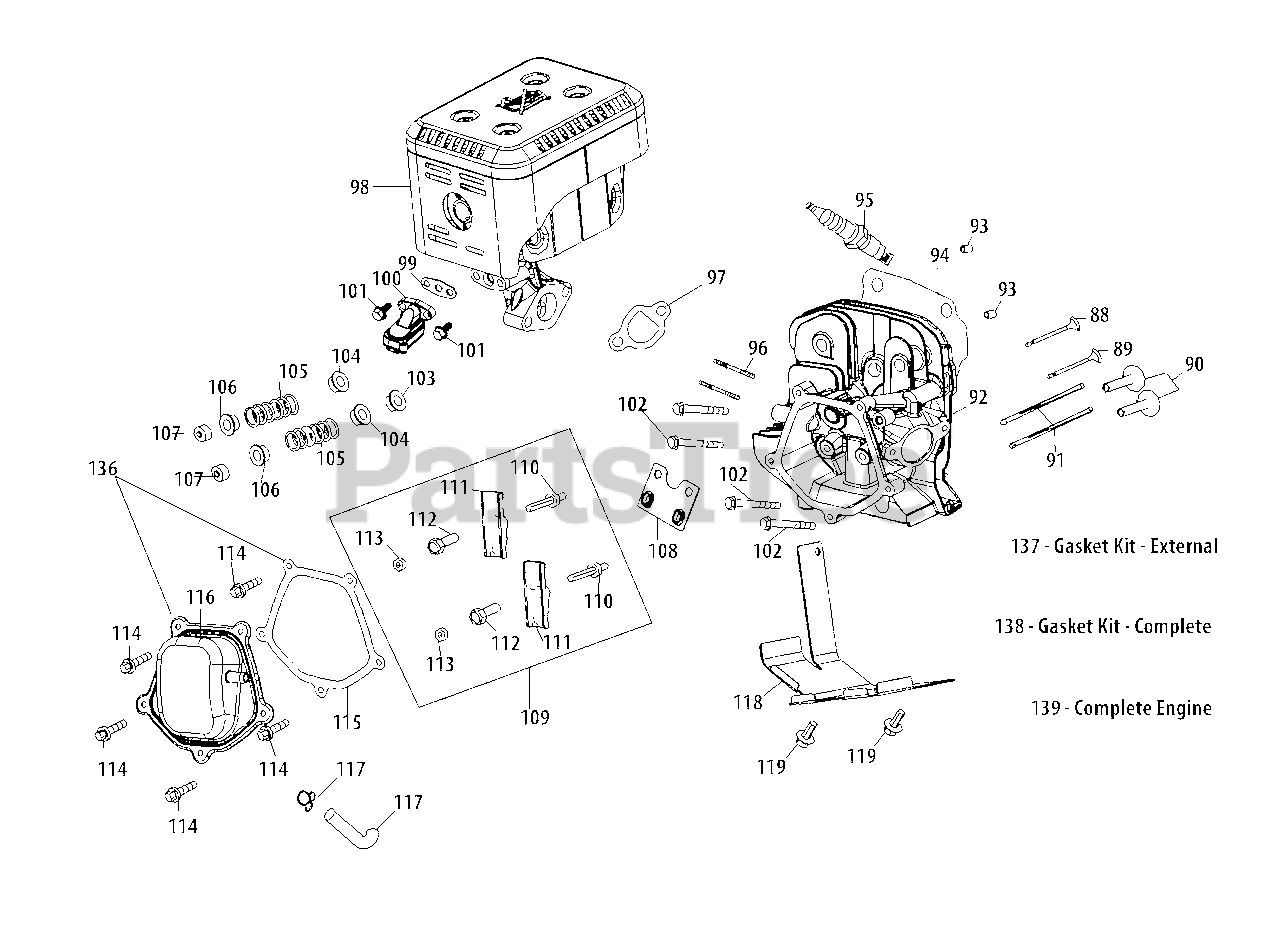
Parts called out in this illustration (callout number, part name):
88	Valve Kit
89	Valve Kit
90	Tappet
91	Push Rod Kit
92	Cylinder Head Kit
92	Cylinder Head Assembly
93	Dowel Pin 12×20
94	Gasket, Cylinder Head
95	Spark Plug/F6Rtc
96	Stud M8×48.5
96	Muffler Stud Assembly
97	Exhaust Pipe Gasket
98	Muffler Assembly
99	Secondary Air Gasket
100	Reed Valve Assembly
101	Bolt M6×16
102	Bolt M10×1.25×80
103	Intake Valve Seal
104	Valve Spring Retainer
105	Valve Spring
106	Retainer, Ex.Valve Spring
107	Adjuster, Exh Valve
108	Push Rod Guide
109	Rocker Arm Assembly
110	Bolt, Pivot
111	Rocker Arm
112	Adjusting Nut ,Valve
113	Nut, Pivot Locking
114	Valve Cover Bolt
115	Valve Cover Gasket
116	Valve Cover
117	Breather Hose
117	Hose Clamp
118	Air Shield
119	Bolt M6×12
136	Valve Cover Kit
137	Gasket Kit - External
138	Gasket Kit - Complete
139	Complete Engine
